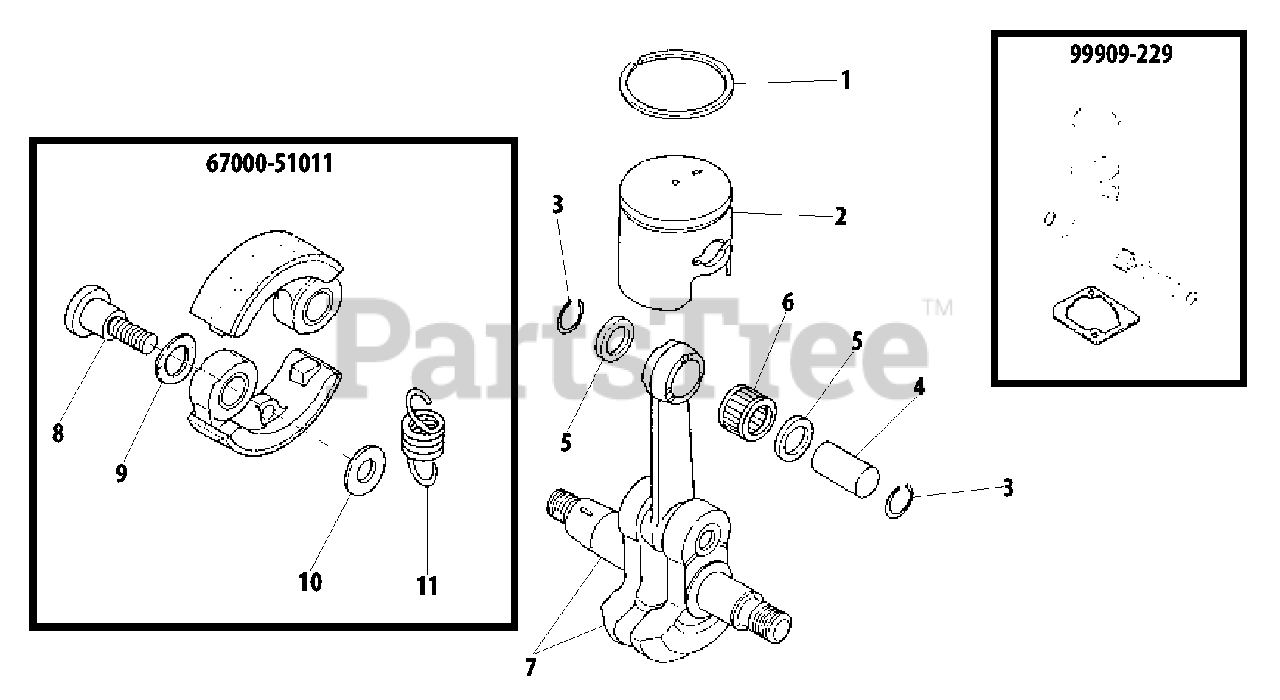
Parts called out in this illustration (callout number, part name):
1	RING, PISTON
2	PISTON
3	RING, SNAP
4	PIN, PISTON
5	WASHER, THRUST
6	BEARING, NEEDLE
7	CRANKSHAFT
8	BOLT
9	WASHER, SPRING
10	WASHER 6 MM
11	SPRING, CLUTCH
67000-51011	SHOE ASSY, CLUTCH
99909-229	PISTON KIT
